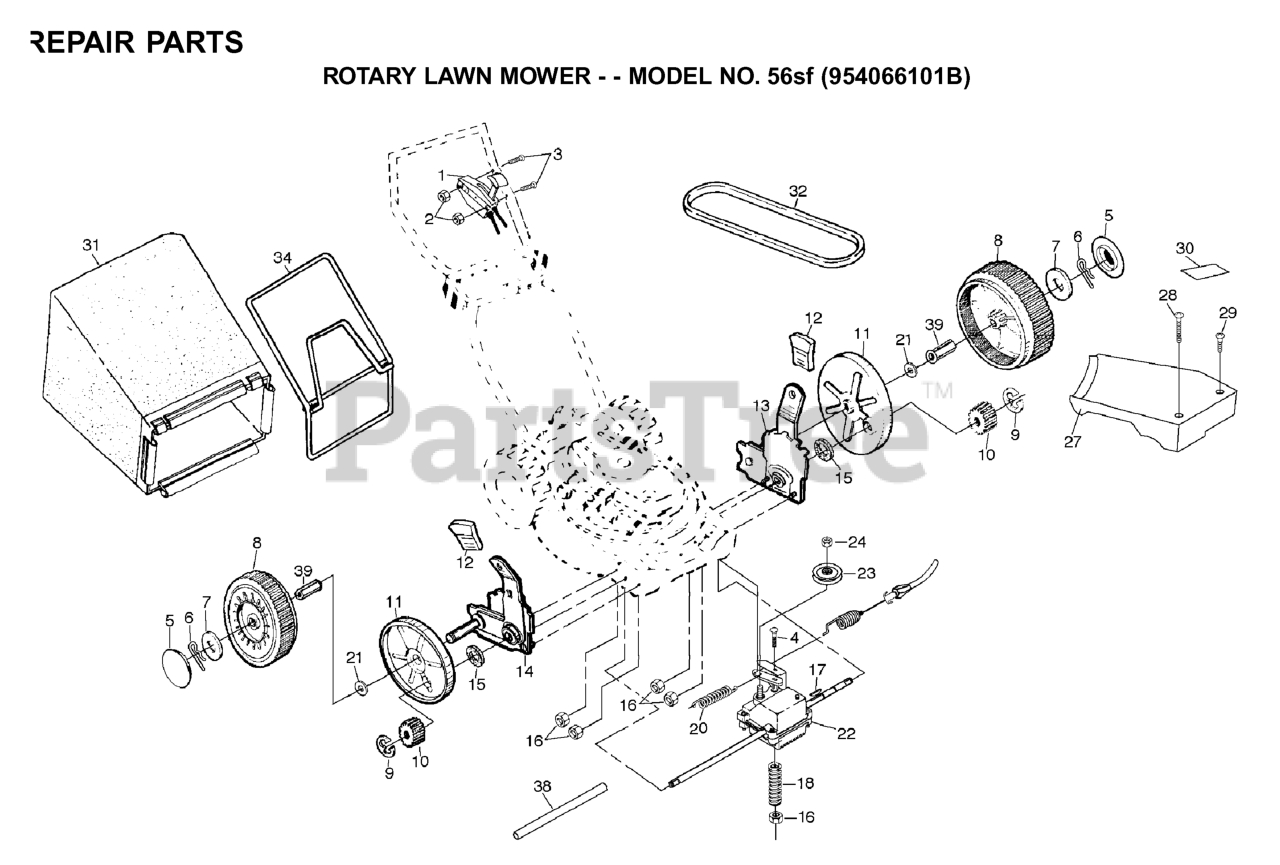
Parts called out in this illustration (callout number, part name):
1	DRIVE CONTROL
2	NUT
3	SCREW 1/4-20 X 2.12
6	RETAINER CLIP PM
8	DRIVE WHEEL
9	E-RING 7/16 RE
10	PINION GEAR
11	DUST SHROUD PM
12	SELECTOR KNOB
13	WHEEL ADJUSTER LH
14	BRACKET ADJ 7P RF
16	NUT
17	HI PRO KEY
18	SPRING.EXTENSION
21	WASHER FLUT
22	GEAR CASE ASMBLY
23	PULLEY
24	FLANGED LOCKNUT 3/8-16 ZINC
27	DRIVE COVER-GRAY
29	SCREW
32	BELT DRIVE
34	CATCHER.FRAME.WALK
35	GRASS BAG
38	DRV SHAFT TUBE PM
39	BUSHING PM
